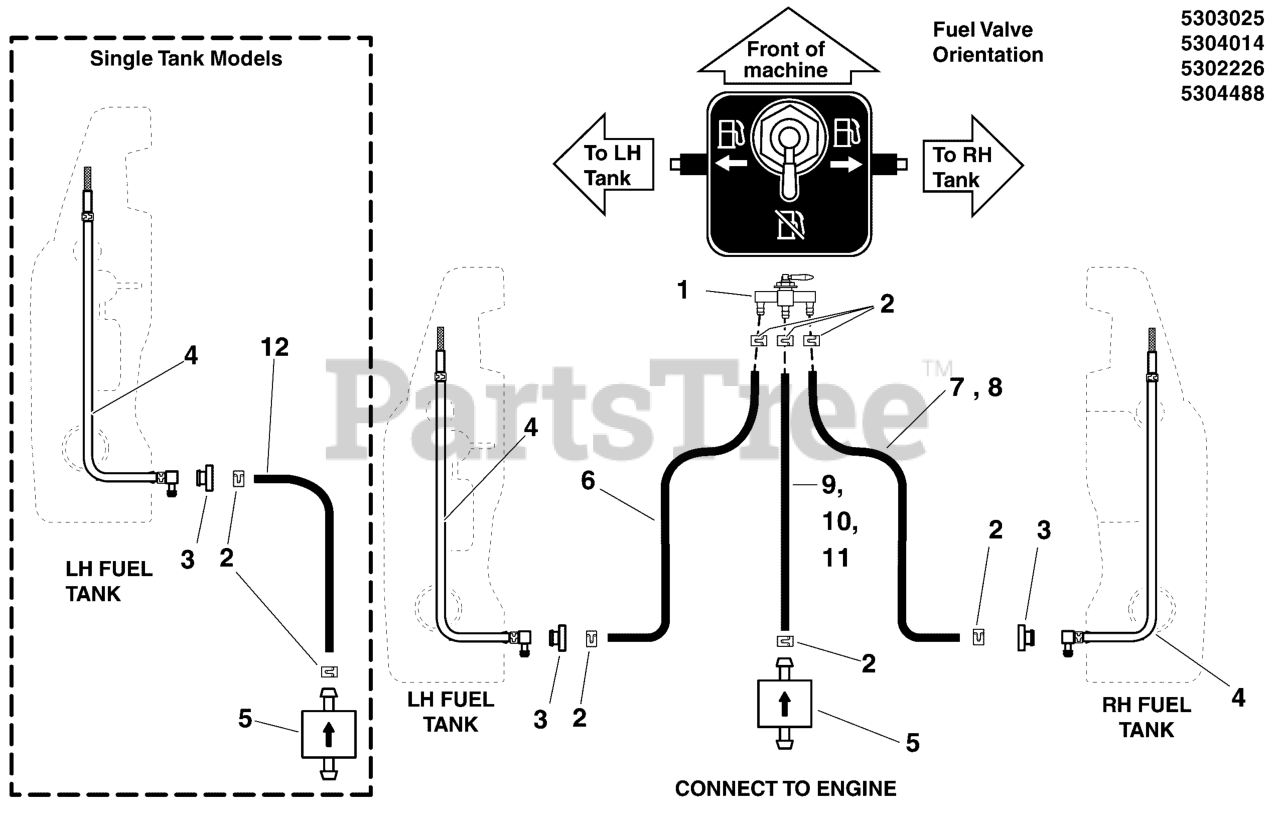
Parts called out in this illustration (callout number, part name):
1	VALVE, FUEL STRAIGHT, OUTLET
2	CLAMP, Hose
3	BUSHING-FUEL TANK RED RUBBER
4	PICKUP TUBE ASSEMBLY, FUEL LINE (SV)
5	FUEL FILTER (SV)
6	1/4" Fuel Line, 22" Long
6	HOSE, 1/4" FUEL, 34.00"
7	1/4" Fuel Line, 58" Long
8	1/4" Fuel Line, 58" Long
9	HOSE, 1/4" FUEL, 34.00"
10	Fuel Line, 25" Long (tank to filter)
11	1/4" Fuel Line, 11" Long
12	1/4" Fuel Line, 37" Long
